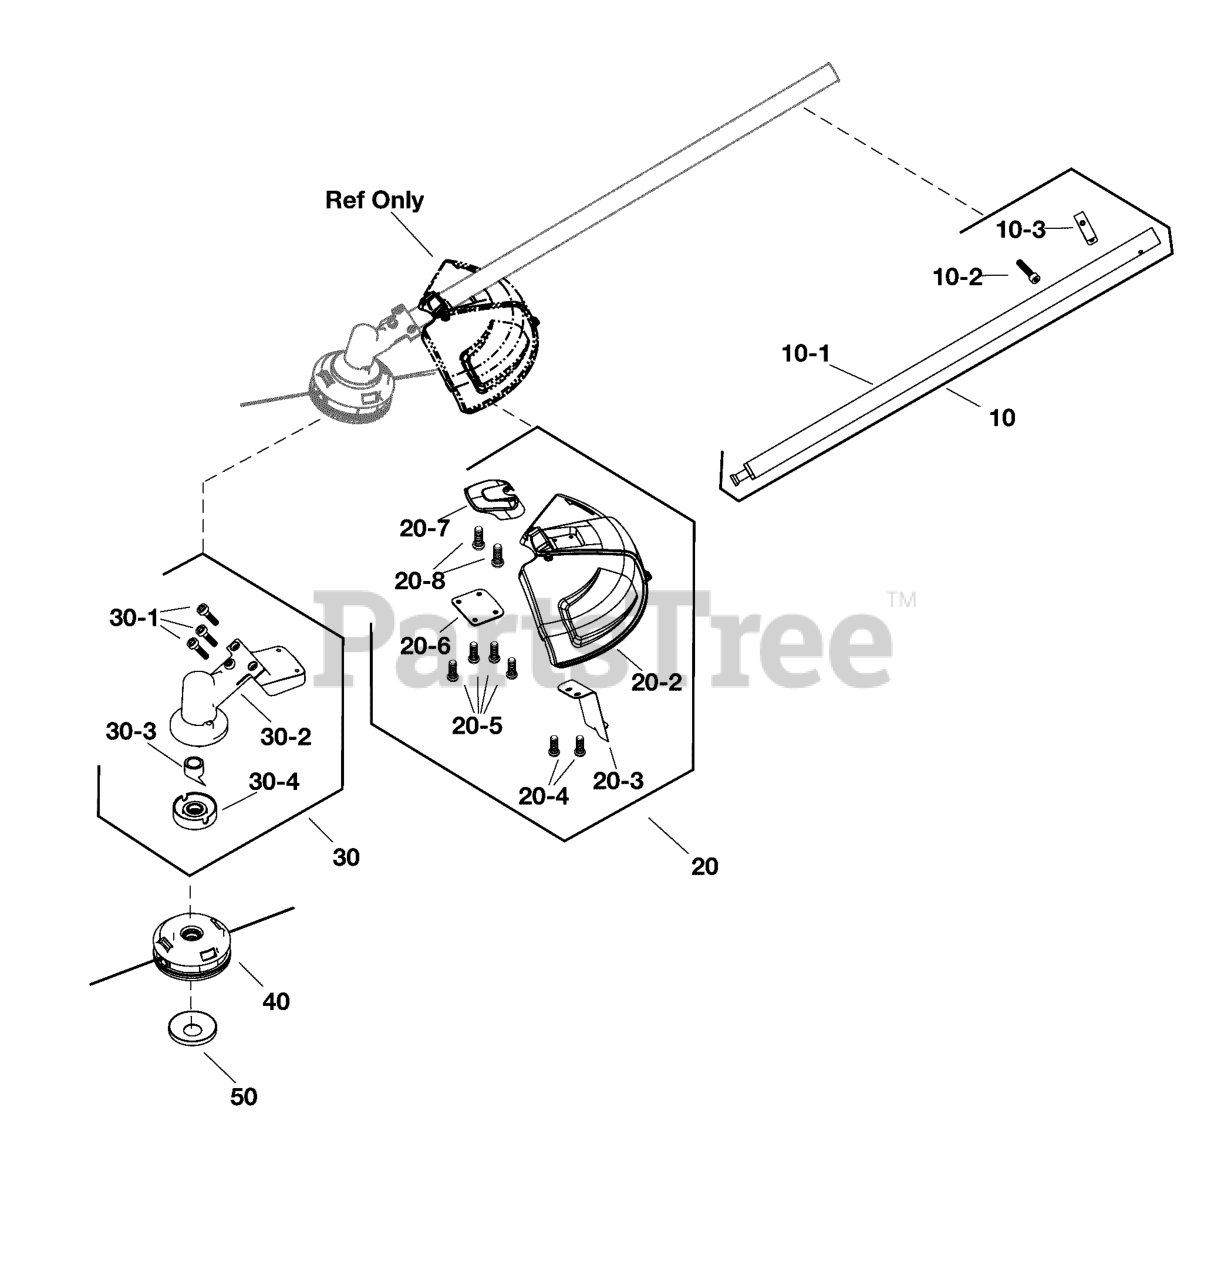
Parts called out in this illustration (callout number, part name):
10	KIT, Shaft
10-1	SHAFT
10-2	SCREW
10-3	CLIP
20	KIT, Guard
20-2	GUARD
20-3	BLADE
20-4	SCREW
20-5	BOLT
20-6	BRACKET
20-7	COVER, Guard
20-8	SCREW
30	KIT, Gear Box
30-1	SCREW
30-2	GEARBOX
30-4	COVER, Gearbox
40	BUMPHEAD
50	COVER, Bumphead
